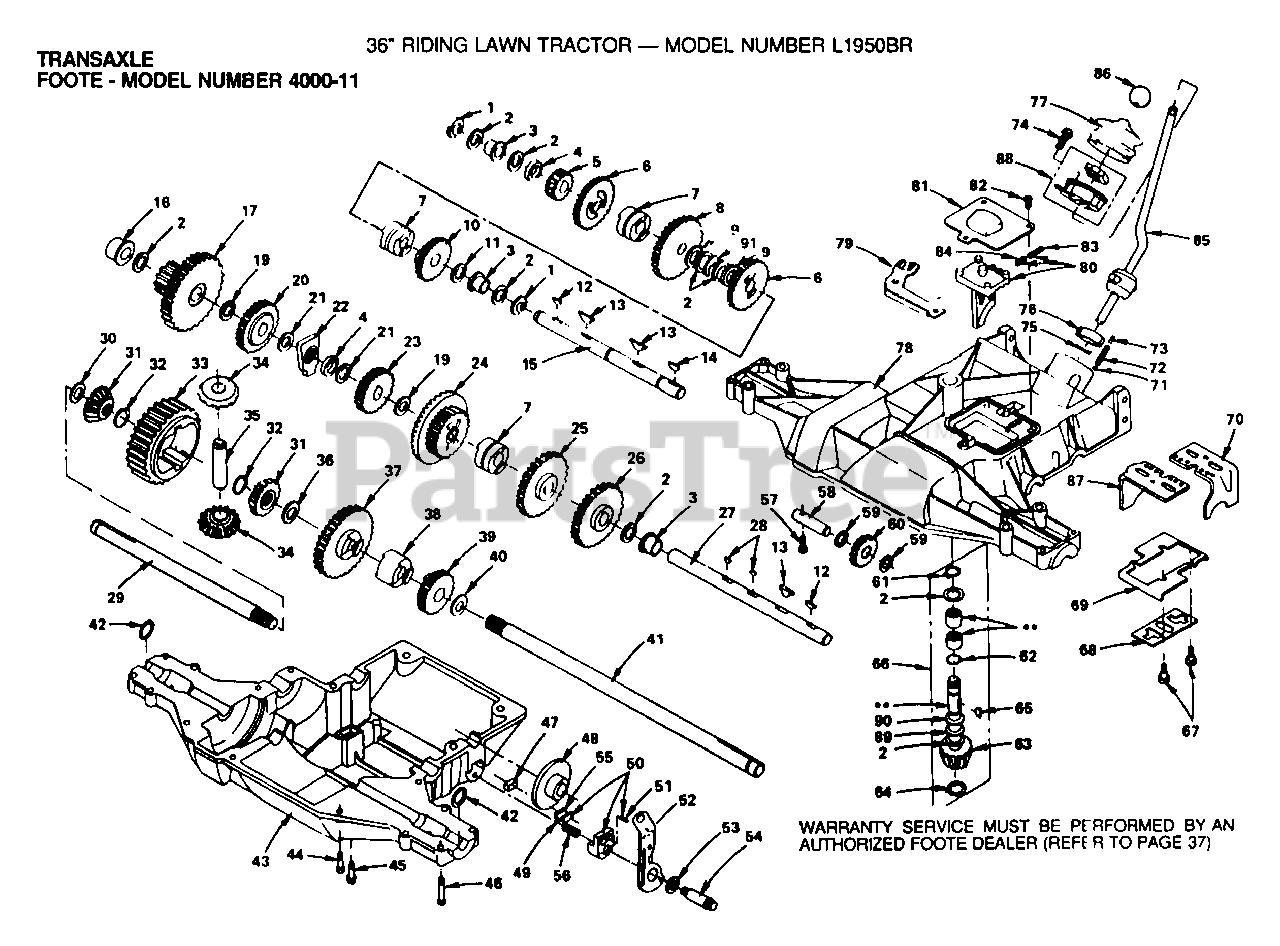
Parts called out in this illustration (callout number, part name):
1	RING, RETAINING
2	WASHER, PLAIN .632 X 1.00 X .060
2	WASHER PLAIN
2	WASHER, PLAIN .632 X 1.00 X .026
5	GEAR, SPUR 13T
6	GEAR, SPUR 25T
8	GEAR, SPUR 30T
10	GEAR, SPUR 20T
11	WASHER PLAIN
12	KEY WOODRUFF #3
14	KEY, WOODRUFF, #61
17	ASSY, GEAR, SPUR 12T
19	WASHER PLAIN
20	GEAR, SPUR 25T
21	WASHER, PLAIN .632 X 1.00 X .026
22	ASSY, SUPPORT SHAFT
23	GEAR, SPUR 20T
24	ASSY, GEAR SPUR & BEVEL
25	GEAR, SPUR 33T
26	GEAR, SPUR 30T
30	WASHER PLAIN
30	WASHER, PLAIN .758 X 1.25 X .031
31	GEAR MITER 15T
33	GEAR, SPUR, 32T
34	GEAR MITER 15T
35	SHAFT, CROSS
36	WASHER, PLAIN .758 X 1.25 X .031
37	GEAR MITER 35T
39	GEAR, SPUR 22T
40	WASHER PLAIN
44	SCREW 1/4-20 X .875
46	SCREW 1/4-20 X 1.31
47	PUCK, FRICTION
48	DISC, BRAKE
50	SPRING, COMPRESSION
52	ASSY, LEVER
53	WASHER, PLAIN
54	BOLT, SHOULDER
55	PUCK, FRICTION
56	SPRING, COMPRESSION
59	WASHER, PLAIN, 1.00 X .505 X .020
60	ASSY, GEAR, IDLER
61	RING RETAINING
64	RING RETAINING
65	KEY WOODRUFF #9
66	ASSY, KIT INPUT SHAFT
80	ASSY, KIT, FORK, SHIFTER
81	PLATE
85	ASSY, LEVER, SHIFT
88	ASSY, COMPONENT
89	WASHER PLAIN
90	WASHER PLAIN
91	RING RETAINING
